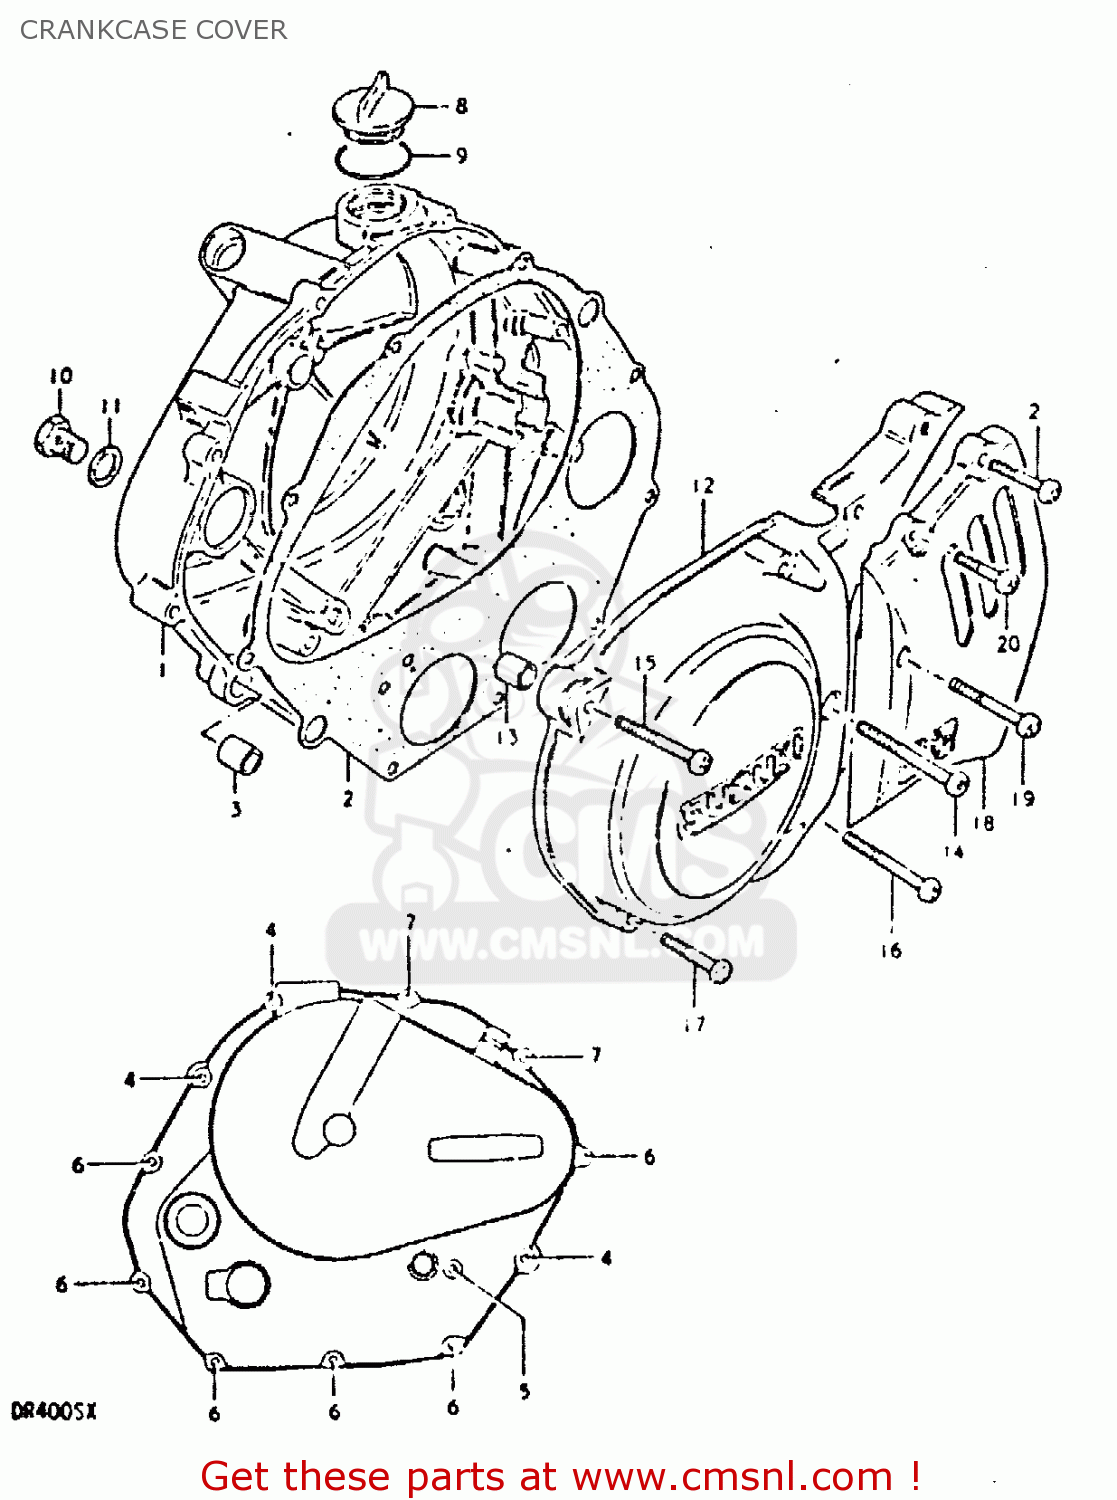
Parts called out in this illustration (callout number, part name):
1	COVER,CLUTCH
2	GASKET,CLUTCH COVER (MCA)
3	PIN
4	SCREW
5	SCREW
6	BOLT (6X35)
7	BOLT
8	CAP
9	O RING(D:2.2,ID:32)
10	PLUG (14X12)
11	GASKET(14X19.2X2) (NAS)
12	COVER
13	PIN
14	BOLT
15	SCREW
16	BOLT
17	BOLT 6X95
18	COVER,SPROCKET
19	SCREW
20	BOLT
21	BOLT
